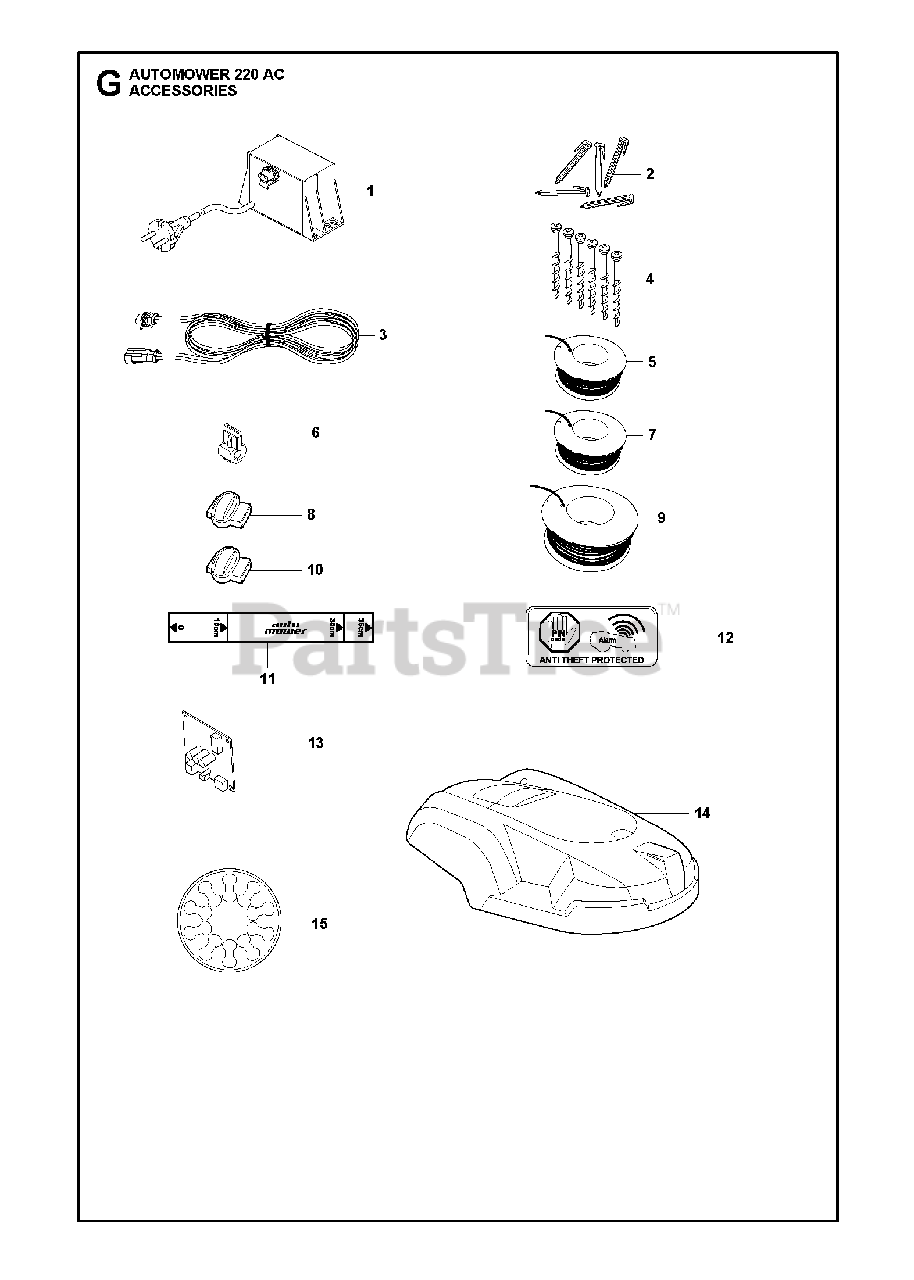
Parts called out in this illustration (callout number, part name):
1	TRANSFORMER
1	TRANSFORMER/US
2	STAPLES (100 CT BAG)
2	STAPLE 100 PCS BLISTE
3	LOW VOLT WIRING
4	SCREW KIT CS
4	SCREW 3 PCS, BLISTER PACK
5	LOOP WIRE 150M
5	WIRE 150M BLISTER
6	BRAKER
6	Connector, 5 Pcs Blist
7	LOOP WIRE 250M
8	SPLICE KIT
8	Splicer Coupler, 5 Pcs
9	Wire, 500M
10	SPLICE CONNECTOR 50 PCS/PK
11	RULER / CENTIMETERS
13	PRINTED CIRCUIT ASSY
14	BODY EARTH, BROWN
14	BODY AIR, CREAM WHITE
14	BODY WATER, DARK BLUE
14	BODY FIRE, ORANGE
